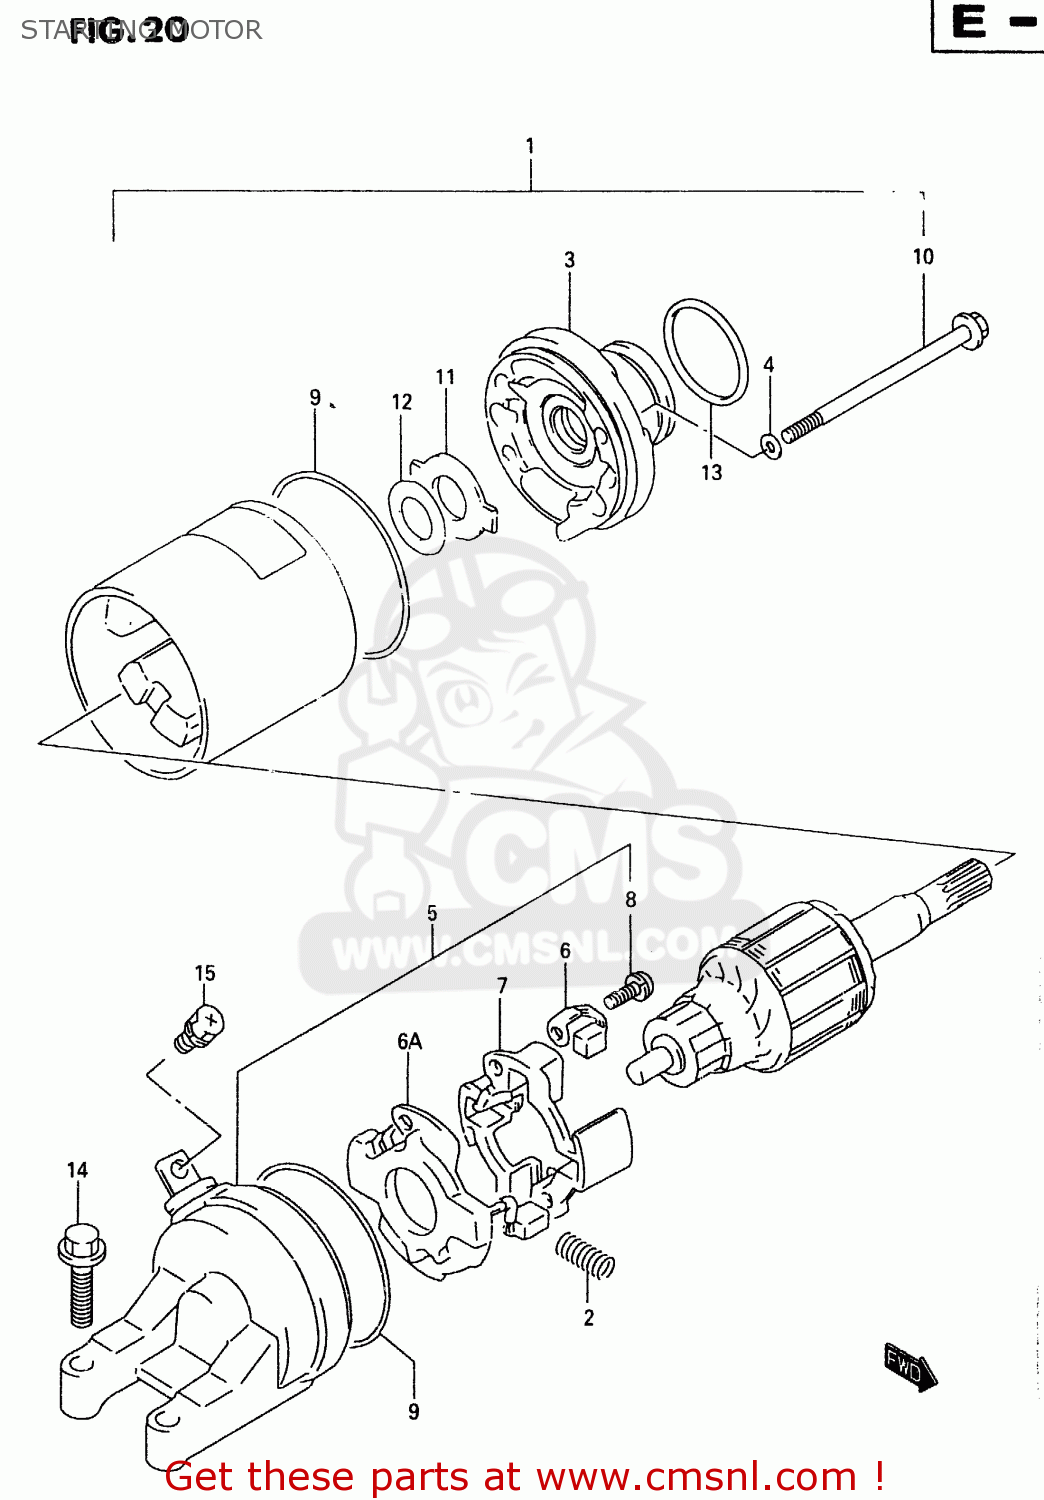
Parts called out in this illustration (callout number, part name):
1	MOTOR ASSEMBLY,STARTING
2	SPRING
3	BRACKET
4	O RING
5	FRAME ASSY,COMMUTATOR END
6	BRUSH
6A	BRUSH SUB ASSY,STARTER
7	HOLDER,BRUSH
8	SCREW
9	O RING
10	BOLT
11	PLATE,LOCK
12	SHIM
13	O RING(D:3,ID:24.5)
14	SCREW (6X25)
15	SCREW(5X8)
